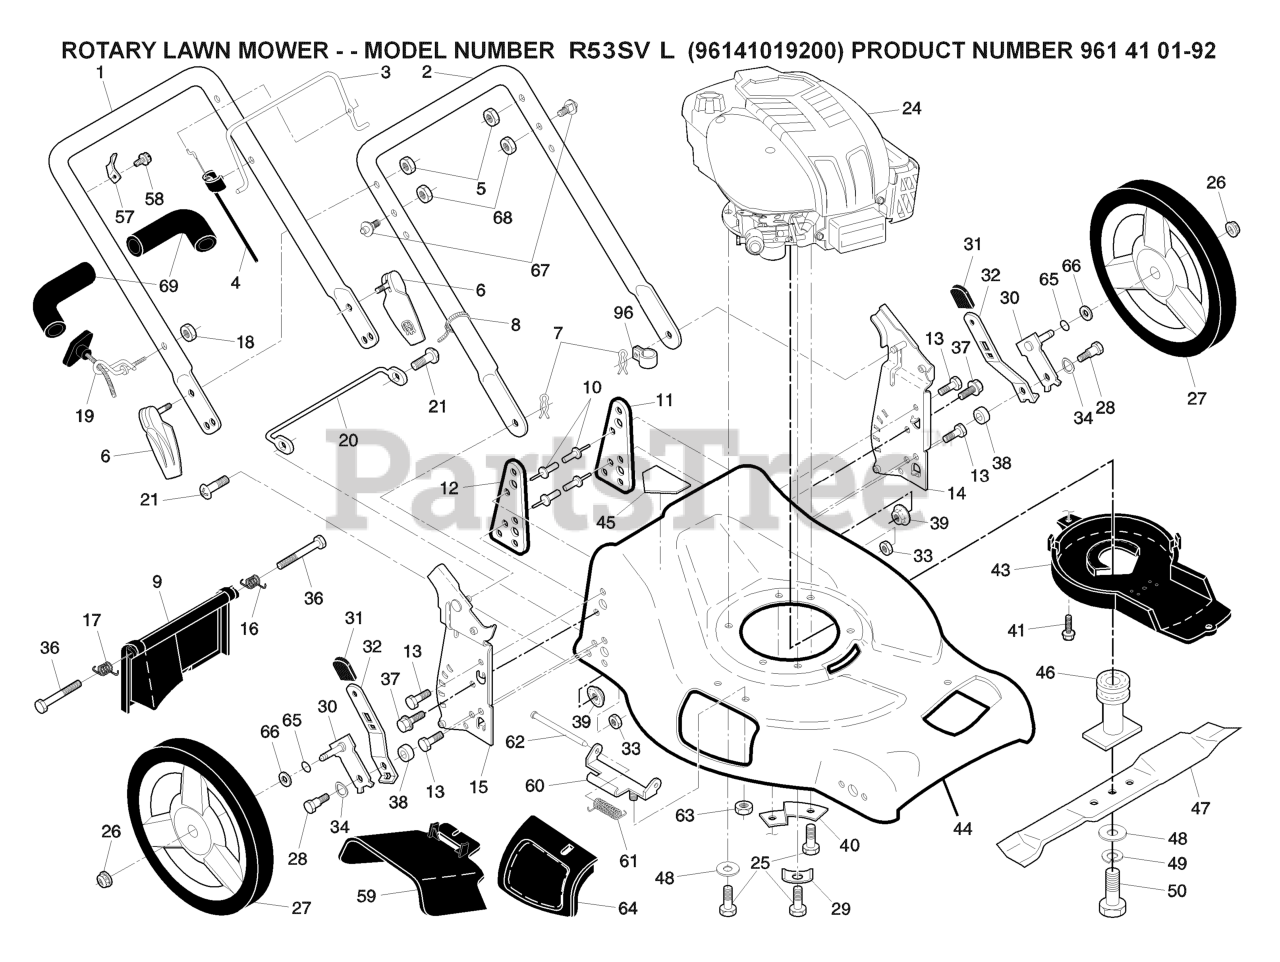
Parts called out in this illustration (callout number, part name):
2	HANDLE.LOWER.ECON.PNT
3	BAIL CONTROL
4	CABLE.ASM.ZONE.CONTROL
5	NUT.HEX.FLANGE.1/4
6	ASM.QUICK.RELEASE
7	HAIRPIN COTTER
8	TIE GUIDE
9	REAR DOOR ASSEMBLY
10	RIVET BLIND
11	BRACKET.SUPPORT.LH.21.FWGD
12	SUPPORT BRACKET RH
13	SCREW 14-20 X 5/8
14	BRACKET.ASM.HND.21FG.EZ.L.HW
15	BRACKET.ASM.HNDL/HW.RT.21.PNT
16	SPRING.REAR.DOOR.EZ.21.LT
17	SPRING.REAR.DOOR.EZ.21.RT
18	NUT
19	RB GUIDE.ROPE.STD.BLK.ZIN WSL
21	SCREW
25	BOLT 3/8-16X1-1/8
26	NUT.HEX.FLANGE.3/8-16.LOCKNUT
27	WHEEL ASSY
28	SHOULDER BOLT 5/16-18
29	WASHER.ENGINE.BZP
30	ARM.ASM.AXLE.REAR.5/9.POS.BZP
31	SELECTOR KNOB
32	SELECTOR SPRING
33	NUT.71038.31-18.HEX.NYLOCK
34	WASHER.CURVED.CYLINDRICAL
37	BOLT.FIN.HEX.5/16-18X3/4
38	SPACER.HEIGHT.ADJUSTER
39	NUT.FLANGE.5/16
40	BRACKET
41	SCREW.HEX.WSH
43	DEBRIS SHIELD
44	KIT.HSG.21.FGD.MC.ORG.CE SYM
45	DECAL.INTERNATIONL.CUTFINGER
46	Blade Adapter / Pulley
47	BLADE.21.PUSH
48	WASHER,HARDEN
49	LOCKWASHER
50	SCREW, HEX HD 3/8-24 X 1-3/8
57	BRACKET
59	DEFLECTOR.CLIPPIN.21.FGD
60	BRACKET.ASM.HINGE.21.FWGD.
61	SPRING.TORSION
62	ROD.HINGE.21
63	LOCKNUT.NYLOC.1/4-20
64	DOOR.MULCH.21.REAR.FWGD
65	O-RING..070X.487.NEOPRENE
66	WASHER.FLAT.1/2
67	STUD.QUICK.ADJUST
68	NUT.LOCK.5/16-18
69	GRIP.HANDLE.FOAM.WIDE.(1 SIDE)
96	CLIP.CABLE.BLK
